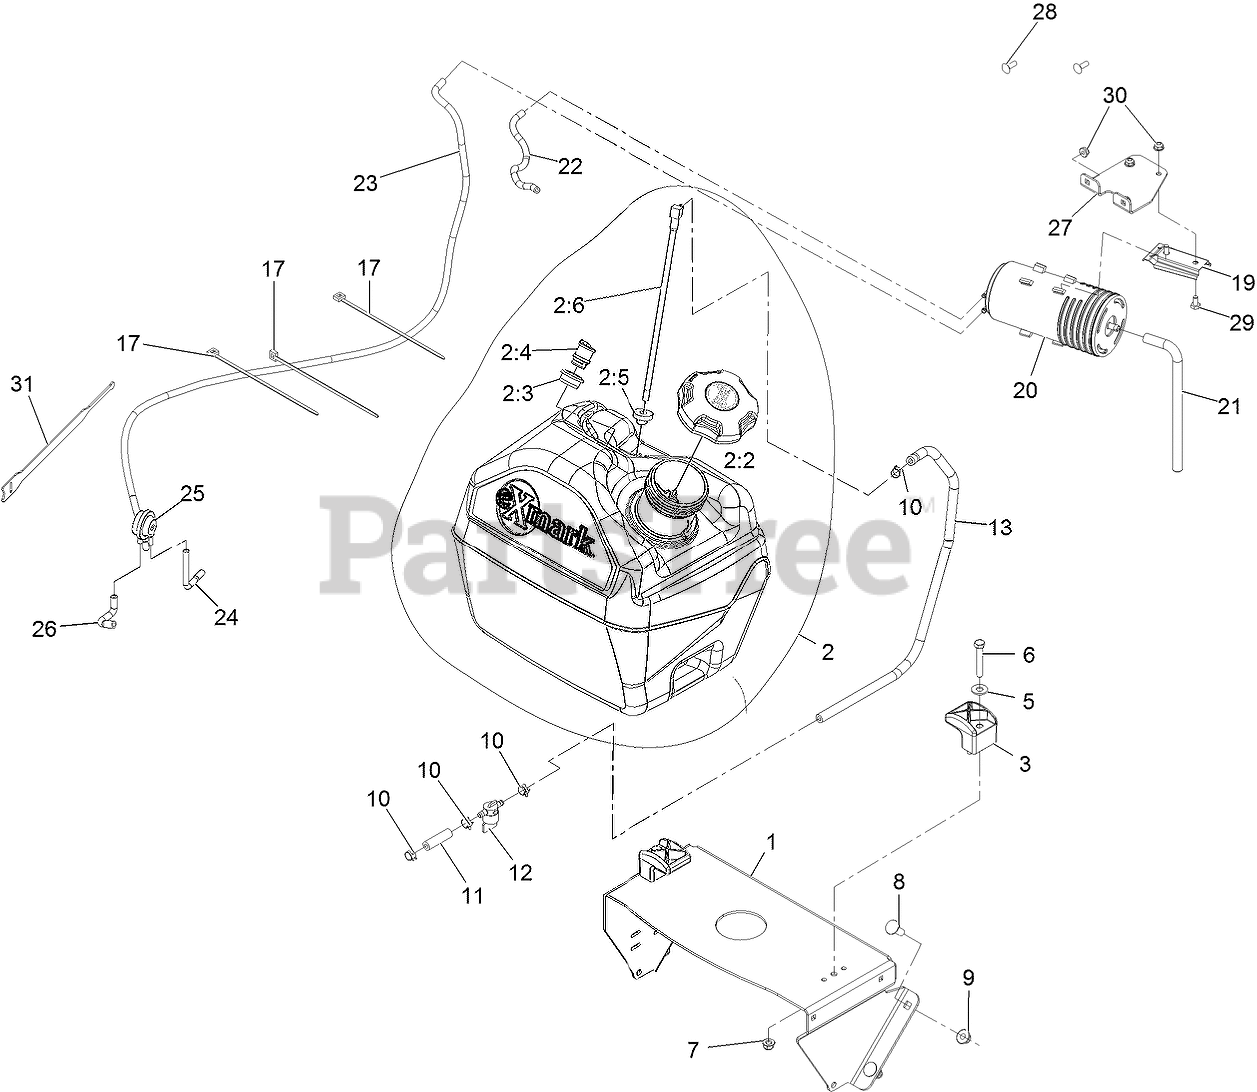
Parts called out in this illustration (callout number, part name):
1	SUPPORT-TANK, FUEL
2	ASM, FUEL TANK 5 GAL
2:2	CAP-FUEL, RATCHETING
2:3	GROMMET
2:4	VALVE-VENT, FUEL
2:5	BUSHING
5	WASHER-FLAT
6	SCREW-HH
7	NUT-HF, NI
8	SCREW-CARR
9	NUT-HF, NI
10	CLAMP-HOSE
11	HOSE-FUEL
12	VALVE-FUEL
13	HOSE-LINE, GAS
17	TIE-PLASTIC
19	BRACKET-CANISTER, CARBON
20	CANISTER-CARBON, 800CC
21	HOSE-VENT, CANISTER
22	HOSE-EMISSIONS
23	HOSE-VENT, FORMED
24	HOSE-VENT, FORMED
25	VALVE-CONTROL, VACUUM
26	HOSE-VENT, FORMED
27	BRACKET-MOUNTING, CANISTE
28	BOLT-CARR
29	SCREW-HH
31	STRAP-VELCRO, CABLE TIE
